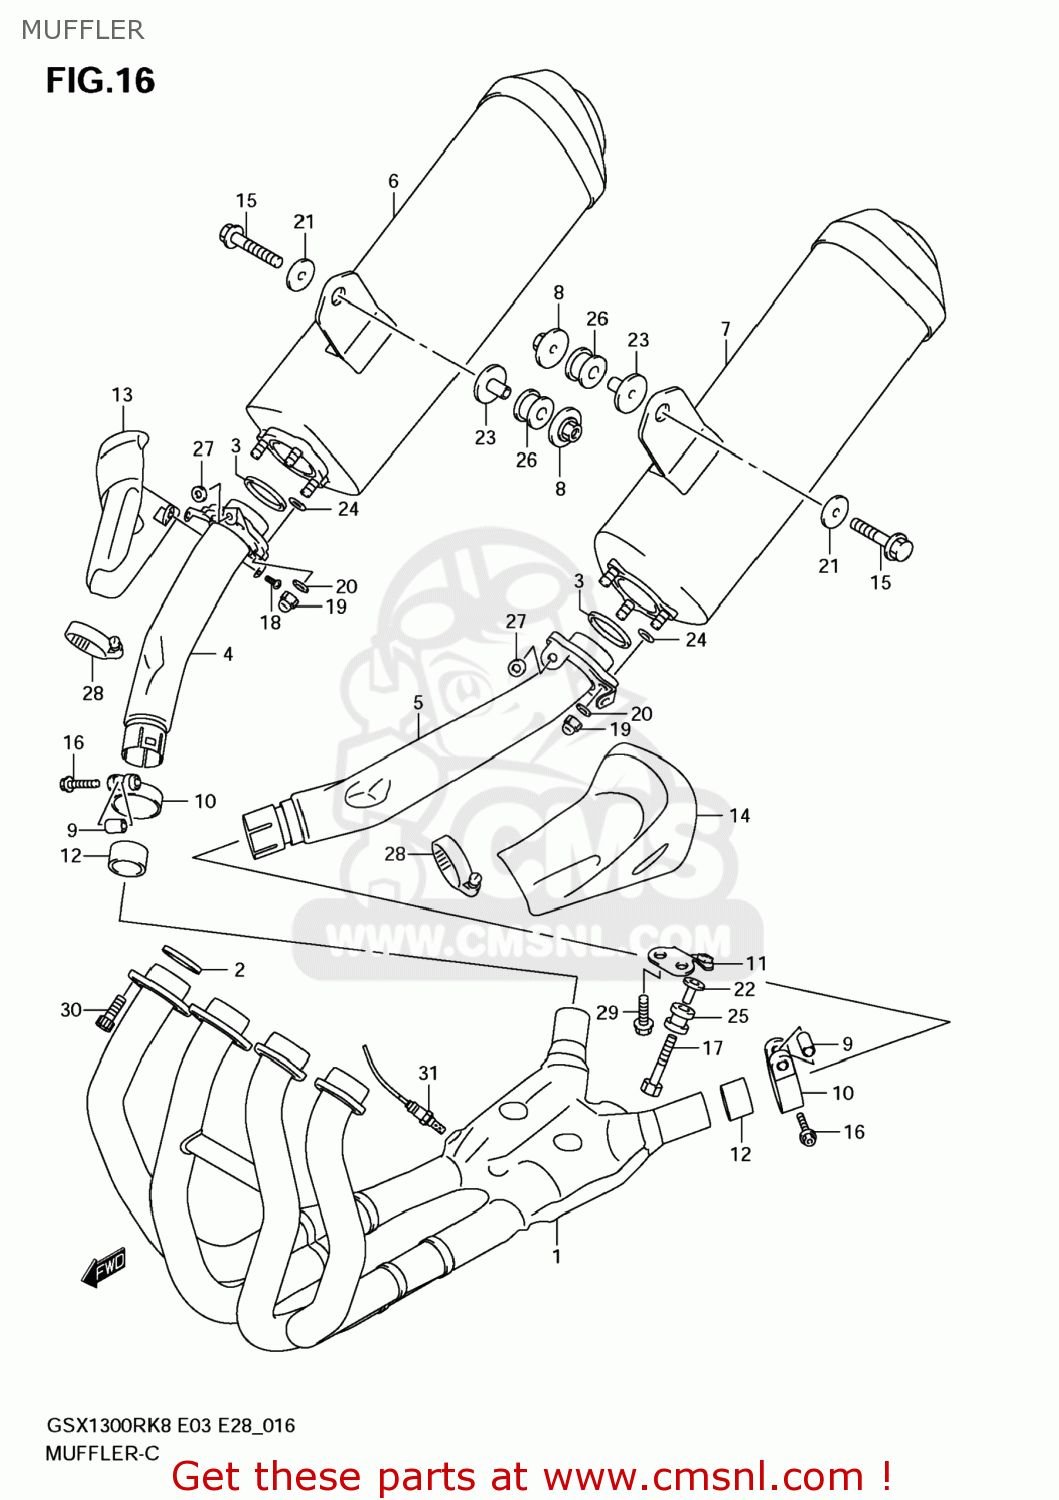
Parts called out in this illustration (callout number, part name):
1	EXHAUST
2	GASKET,EXHAUST PIPE (NAS)
3	GASKET,MUFFLER JOINT
4	PIPE,JOINT,R
5	PIPE,JOINT,L
6	BODY,MUF,R
7	BODY COMP,MUF,
8	NUT,MUFFLER SUPPORT RR
9	SPACER,CLAMP
10	CLAMP,CONNECTOR MUFFLER
11	BRACKET,EXHAUST SUPPORT
12	CONNECTOR,MUFFLER
13	COVER,MUFFLER FR,R
14	COVER,MUFFLER FR,L
15	BOLT(8X45)
16	BOLT(8X40)
17	BOLT 8X45
18	SCREW(6X12)
19	NUT
20	WASHER(8.5X18X1.6)
21	WASHER(8.5X28X1.5)
22	SPACER(8.6X12X24.2)
23	SPACER(8.6X12X25)
24	O RING(D:1.9,ID:7.8)
25	CUSHION
26	CUSHION
27	CUSHION
28	CLAMP
29	BOLT
30	BOLT
31	SENSOR,OXYGEN
